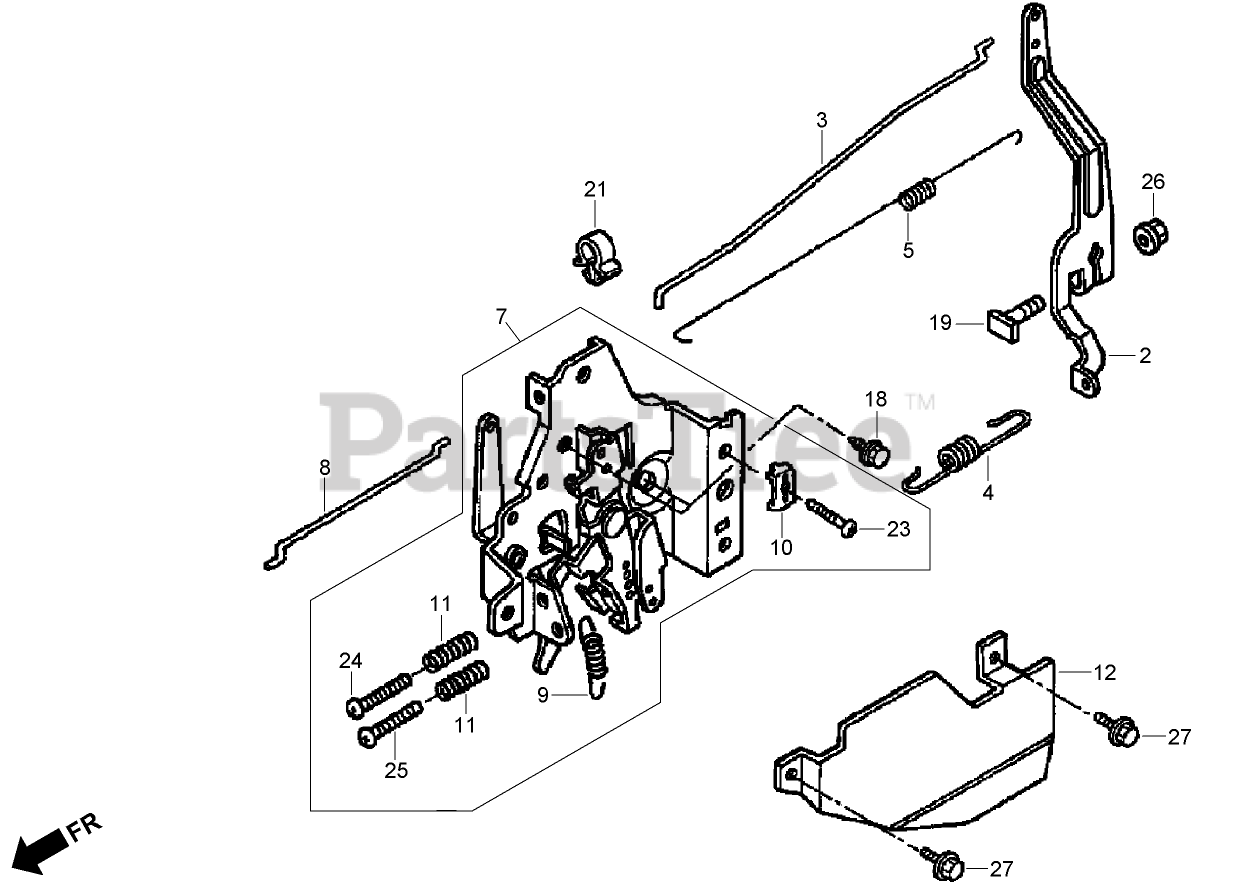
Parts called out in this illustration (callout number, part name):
2	Arm-Governor
3	Rod-Governor
4	Spring-Governor (STD)
5	SPRING-RETURN, THROTTLE
7	CONTROL ASM
8	Rod-Choke
9	Spring-Lever
10	Holder-Cable
11	SPRING-ADJUSTING, CONTROL
12	Protector-Control
18	BOLT-FLANGE (6X12) (C T200)
19	BOLT-ARM, GOVERNOR
21	CLIP-HARNESS, WIRE
23	Screw-Pan (5X16)
24	Screw-Pan (5X20)
25	Screw-Pan (5X28)
26	NUT-FLANGE (6 mm)
27	Bolt-Flange (6X10)
